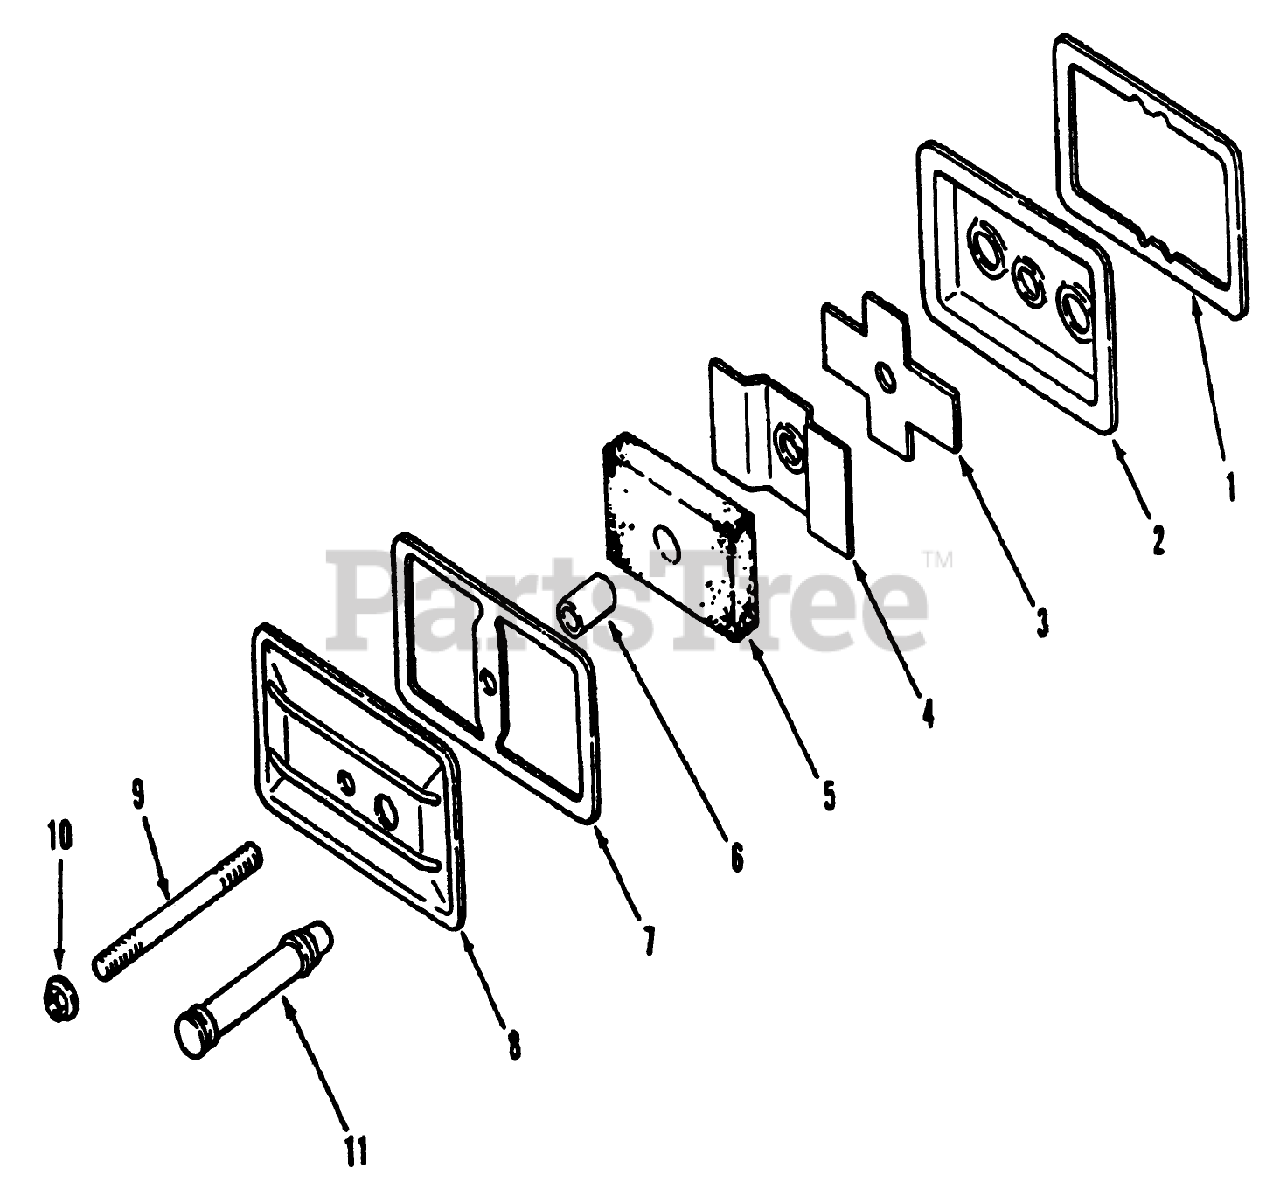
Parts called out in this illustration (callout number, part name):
1	KOHLER 235048
2	KOHLER 235631
3	KOHLER 235047
4	KOHLER 270146
5	KOHLER 47-050-01
6	KOHLER 231032
7	KOHLER 275144
8	KOHLER 47-096-01
9	KOHLER 275220
10	KOHLER X-799-1
11	KOHLER 47-326-03
